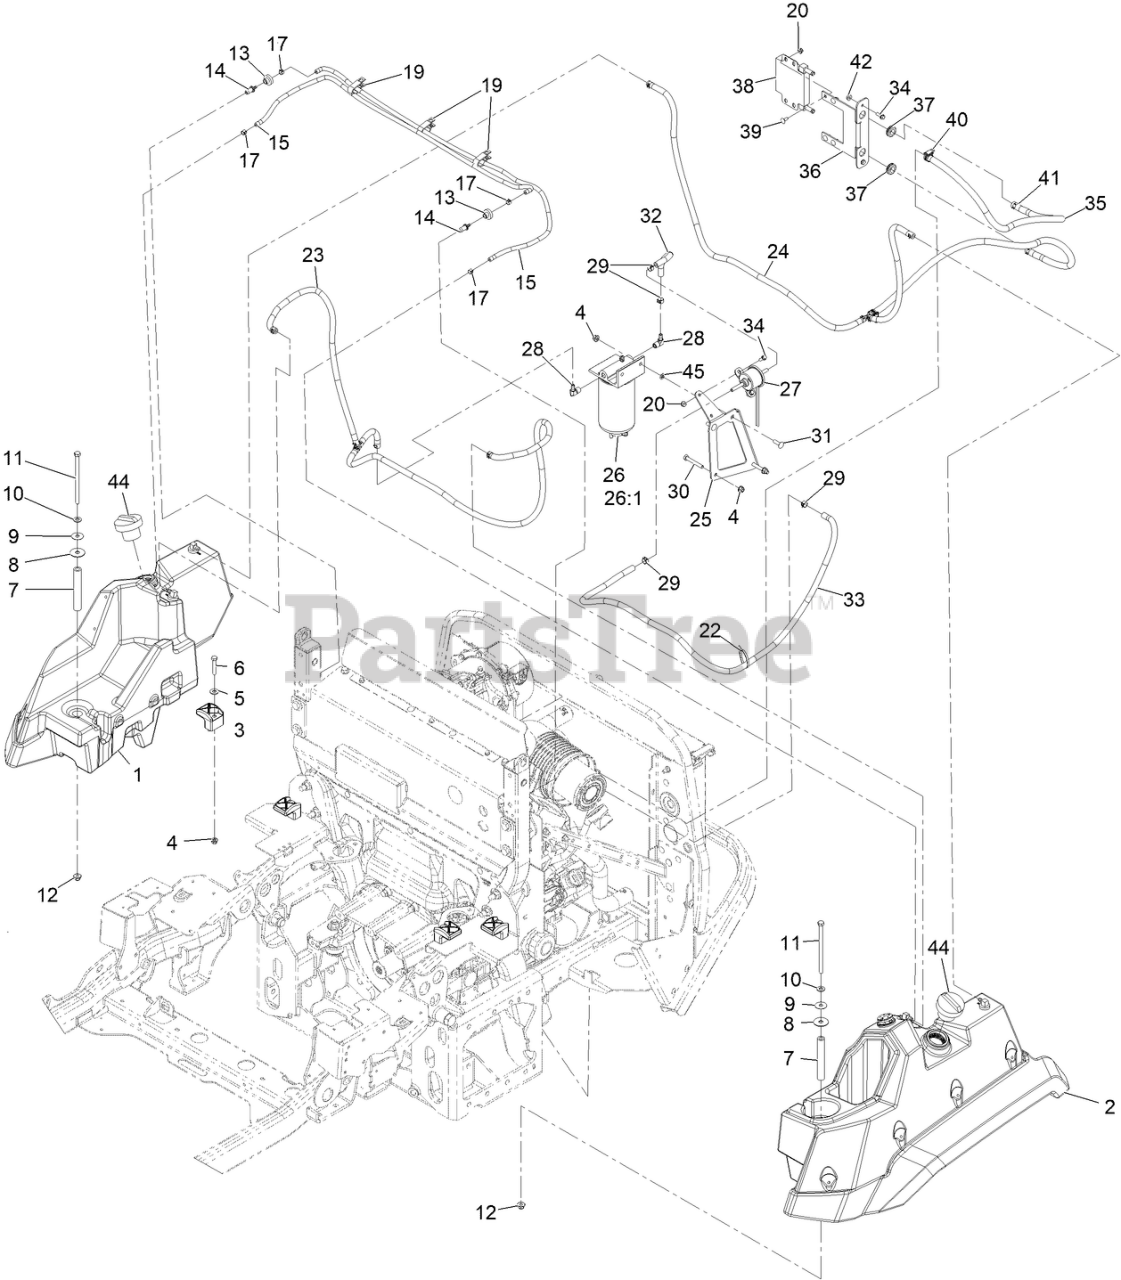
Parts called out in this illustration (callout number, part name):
1	RH FUEL TANK ASM
2	LH FUEL TANK ASM
4	NUT-HF, NI
5	WASHER-FLAT
6	SCREW-HH
7	TUBE-SPACER
8	WASHER-RUBBER
9	WASHER-PLAIN
10	WASHER-FLAT
11	SCREW-HH
12	NUT-HF, NI
13	BUSHING
14	FITTING-ORIFICE, STRAIGHT
15	HOSE-VENT, TANK
17	CLAMP-HOSE
19	CLAMP-HOSE
22	TIE-CABLE
23	FUEL SUCTION LINE ASM
24	HOSE ASM-FUEL, TEE
25	BRKT-FUEL FILTER
26	FILTER-WATER/FUEL SEPERATOR
26:1	FILTER-FUEL/WATER SEP.
27	PUMP-FUEL, ELECTRIC
28	FITTING-HYD, 90
29	CLAMP-HOSE
30	SCREW-HH
31	SCREW-CARR
32	HOSE-FUEL
33	HOSE-FUEL
34	SCREW-HWH
35	HOSE-FUEL
36	MOUNT-COOLER, FUEL
37	GROMMET
38	COOLER-OIL
39	SCREW-CARR
40	Clamp-Hose
41	CLAMP-HOSE
44	CAP-FUEL, DIESEL (ULTRA LOW SULFUR)
45	RING-RETAINING, BOLT
